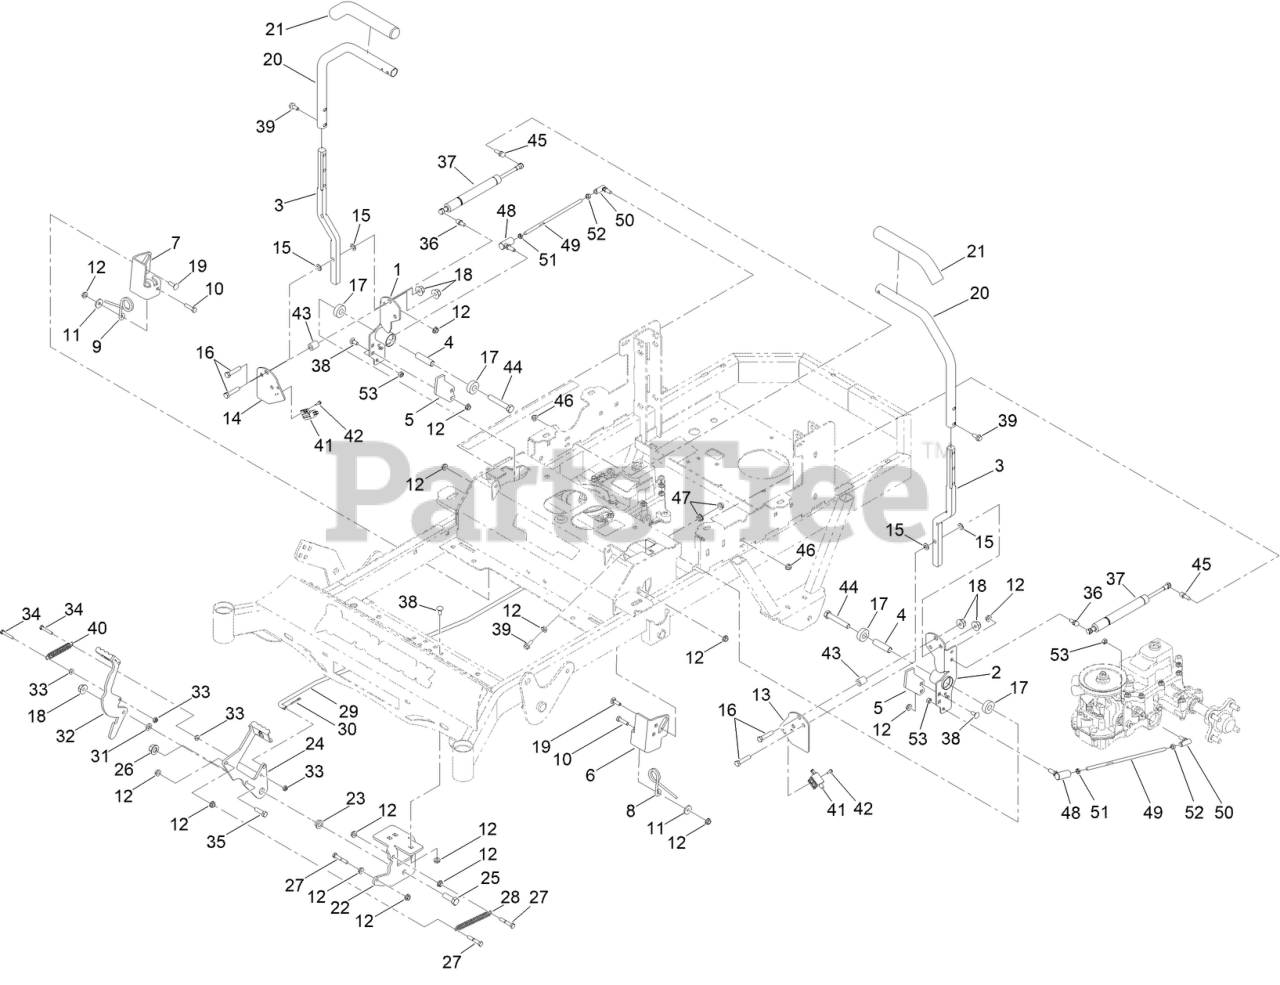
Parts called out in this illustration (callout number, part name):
1	MOTION CONTROL BRKT
2	MOTION CONTROL BRKT
3	HEIGHT ADJUSTABLE CONTROL ARM
4	MWR DRIVE ARM HUB / DECK LIFT ARM SPACER
5	REVERSE DETENT KICK PLATE
6	REVERSE DENTENT SPRING BASE (LH)
7	REVERSE DENTENT SPRING BASE (RH)
8	SPRING- LT REVERSE DETENT
9	SPRING-TORSION
10	SCREW-HH
11	STRIKER POST FENDER WASHER
12	NUT-HF
13	LT CONTROL ARM LIMIT SWITCH PLATE PAINT
14	RT CONTROL ARM LIMIT SWITCH PLATE PAINT
15	3/8 X 3/4 BRONZE WASHER
16	3/8-16 X 1-3/4 HEX C/S GR 2 ZINC
17	5/8IN ID X 1-3/8IN OD X 7/16IN THK BRG
18	3/8-16 NYLON INSERT FLANGE L/NUT YZ
19	5/16-18 X 1 CARRIAGE BOLT GR 8 YZ
20	MOWER DRIVE HANDLE TUBE ABC
21	CONTROL ARM HANDLE GRIP
22	MWR FRAME BRAKE MTG BRKT PAINT
23	1/2IN ID X 3/4IN OD X 3/8IN FLANGE BUSH
24	MWR BRAKE LOCK LEVER ASSY PAINTED
25	SCREW-HH
26	NUT-LOCK
28	2020 MWR BRAKE PEDAL TENSION SPRING
29	MWR BRAKE LINKAGE
30	PIN-COTTER
31	3/8 ID X 3/4 OD X .125 THK BRONZE WASHER
32	MWR BRAKE UNLOCK LEVER ASSY PAINTED
33	1/4-20 HEX FLANGE NUT
34	1/4-20 X 1-1/4 HEX C/S GR 2 ZINC
35	SCREW-HH
36	5/16-18X1.286 DAMPER BALL STUD (.562 TL)
37	CONTROL ARM DAMPER
38	BOLT-CARR
39	SCREW-HHF
40	MWR BRAKE PEDAL RELEASE SPRING
41	NO PLUNGER LIMIT SWITCH
42	8-32 X 1/2 IND. HWH SLOT TYPE F TCS ZINC
43	MWR DRIVE ARM SPACER
44	1/2-13 X 3 HEX C/S GR 5 ZINC W/LOCTITE
45	5/16-18X1.286 DAMPER BALL STUD (.562 TL)
46	NUT-HF, NI
47	NUT-HHF, WHIZ
48	CONTROL ARM ROD END LT
49	MWR DRIVE ARM ROD TTQ 400 + 300 TRANS
50	BALLJOINT-RH (W/GROMMET)
51	NUT-JAM
53	5/16-24 NYL INS L/N GR.8 ZC/YEL
